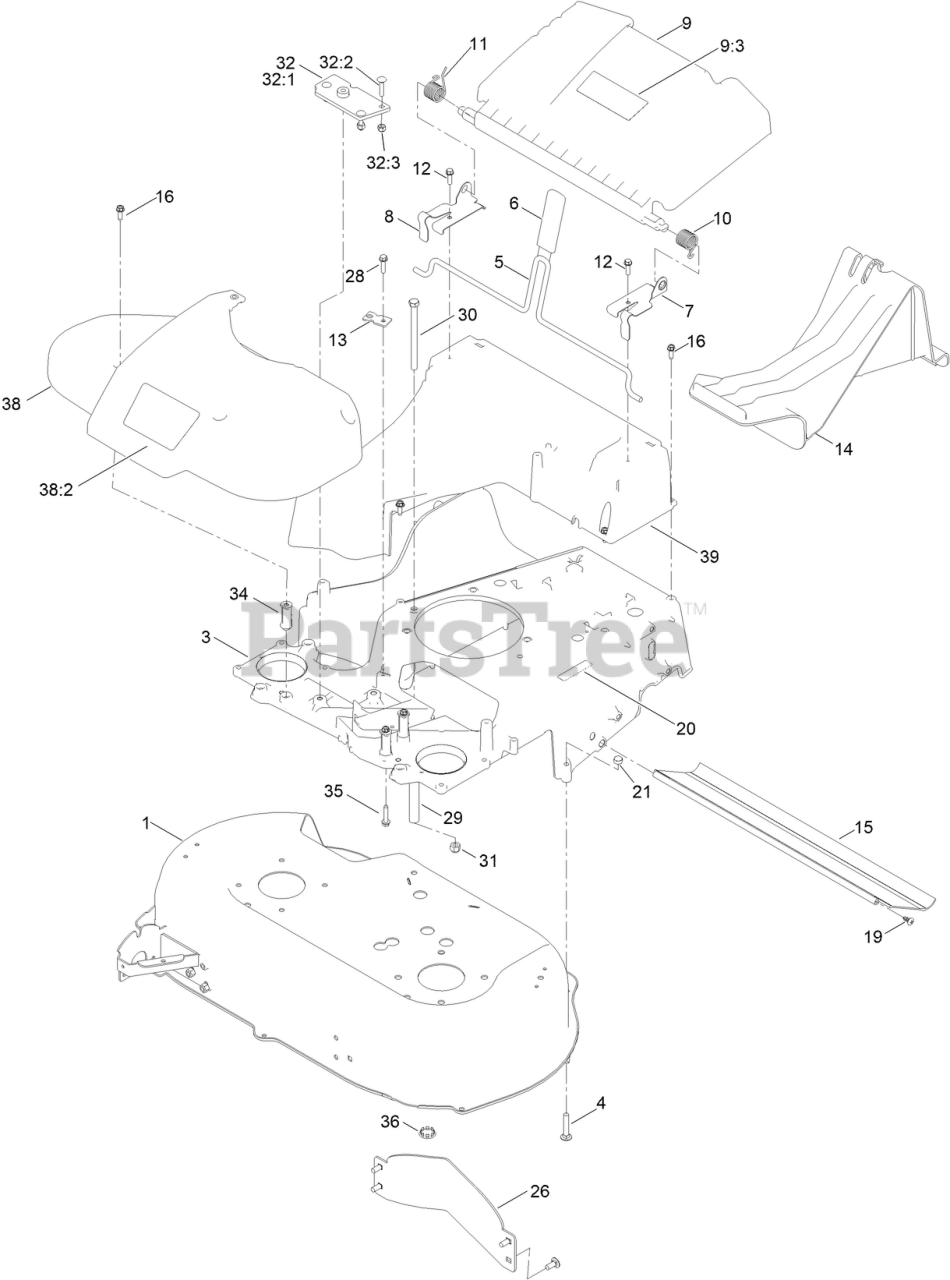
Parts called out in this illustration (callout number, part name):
1	HOUSING ASM
3	FRAME-30"
4	BOLT-CAR
5	ROD-RELEASE, HANDLE
6	GRIP-LEVER
7	BRACKET-DOOR, LH
8	BRACKET-DOOR, RH
9	REAR DEFLECTOR ASM
9:3	DECAL-WARNING
10	SPRING-TORSION
11	SPRING-TORSION
12	SCREW-HWH
13	BRACKET-CABLE, TRACTION
14	PLUG-MULCH
15	SHIELD-TRAILING
16	SCREW-HWHTF
19	SCREW-PTH
20	DECAL-ARRESTOR, SPARK
21	NUT-LOCK, NI
26	BAFFLE-CONTROL
28	SCREW-HWHTF
29	SPACER-SHIELD
30	SCREW-HH
31	NUT-HEX
32	FRAME PLATE KIT
32:1	PLATE-FRAME
32:2	SCREW-CARR
32:3	NUT-LOCK, NI
34	SPACER-FRAME, 30 IN.
35	SCREW-HWHTF
36	PLUG-BUTTON
38	BELT COVER ASM
38:2	DECAL-COVER, BELT
